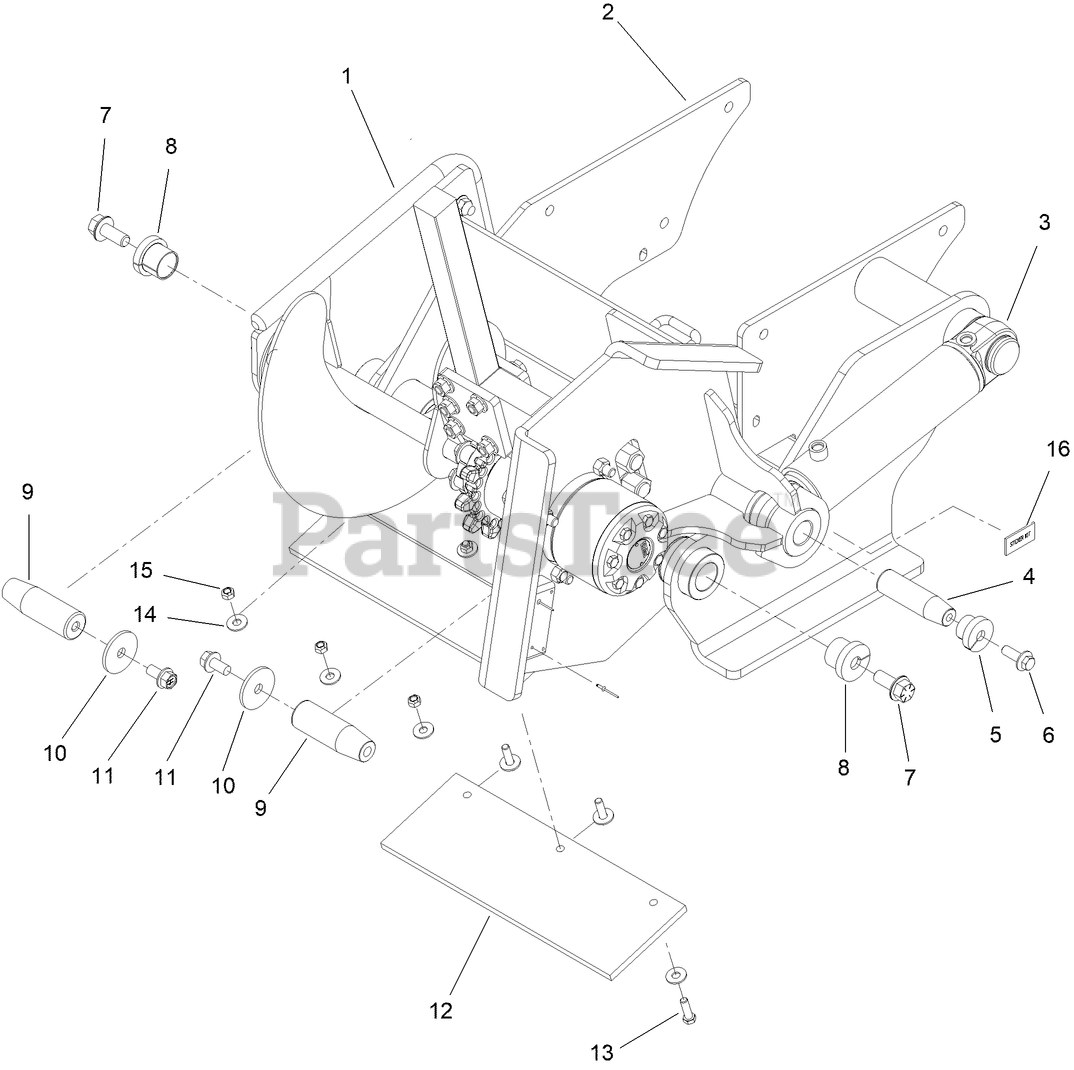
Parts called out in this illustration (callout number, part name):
1	PIVOT ASSEMBLY
2	ATTACHMENT PLATE
3	CYL (2.5 X 1.25 X 8.0)
4	TAPERED PIN (4.50 X 1.25)
5	TAPERED INSERT (1.25")
6	SCREW-HFH
7	FLG BLT (5/8-NC X 1-1/2", GR 8)
8	TAPERED INSERT (1.5")
9	TAPERED PIN (1.500" X 4.600")
10	WASHER (1/2") ZP
11	SCREW-HHF
12	FLAP-SPOILS
13	SCREW-HH
14	WASHER-FLAT
15	NUT-LOCK, NI
16	25531E MAXI SNEAKER TRENCHER DECAL KIT
